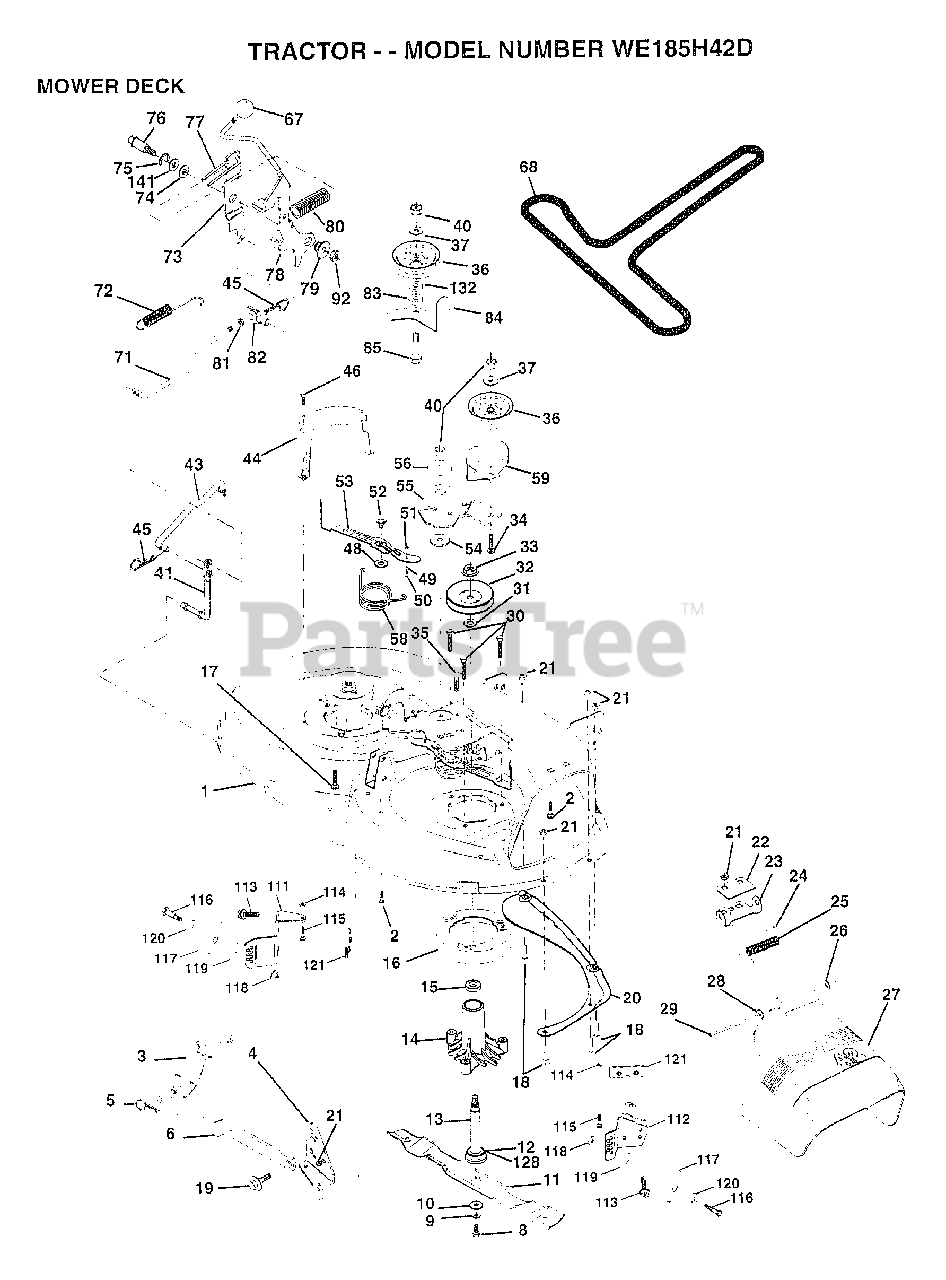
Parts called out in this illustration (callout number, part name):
1	DECK.WELD.42.
2	BOLT
3	BRKT ASM SWAY BAR
4	BRKT DECK SW BAR
8	BLADE BOLT
10	WASHER.HARD.BLADE
11	"BLADE.42"" HIPERF"
12	BEARING.BALL
14	HSG ASM MANDREL
15	BEARING
16	STRIPPER RND MWR
17	BOLT RDHD 3/8-16
18	BOLT
19	BOLT SHD 5/16-18
20	BAFFLE VORTEX 42
22	STIFFENER BRKT
23	DEFLECTOR BRKT
24	CAP-SLEEVE LT
25	SPRING TORSION
26	NUT PUSH M
27	DEFLECTOR.SHIELD
28	WASHER
29	HINGE ROD
30	"SCREW-THD ROLL,WA"
31	WASHER
32	PULLEY.MANDREL.42
34	BOLT
35	XMAS TREE FASTNER
36	FLAT IDLER PULLEY
37	WASHER
41	PIVOT ROD
43	ROD CLUTCH W/NIBS
44	GUARD MAND LH BLK
46	SCREW.1/4-20X5/8
48	HARD SMALL WASHER
49	ROLLER ASM-CAM
50	SHOULDER BOLT
51	LOCKNUT
52	BOLT.SHLD.5/16-18
54	HARDENED WASHER
55	ARM-IDLER
56	SPACER RETAINER
58	SPRING TORSN BRAK
59	GUARD IDLER TUV
67	KNOB.RD.7/16-14
68	BELT.V.T-PATH
71	ROD CLUTCH 38/42
72	RETURN SPRING
73	CLUTCH ARM SECOND
74	WASHER
75	RING
76	SHOULDER BOLT
77	SPRING KEEPER
78	LEVER.ASM.CLUTCH
79	BUSHING
80	SPRING.CLUTCH.MWR
81	NUT
82	TRUNION ADJ
83	WASHER
84	"KEEPER-BELT,FIXED"
85	BOLT RDHD 3/8-16
92	NUT
111	BRACKET.GWHL.LH.
112	BRACKET.GWHL.RH.
113	SCREW
116	BOLT M
117	WHEEL.GAGE.BLK.PL
118	LOCKNUT
119	WASHER
120	WASHER
121	BRACKET.EXTRD.GWL
128	WASHER.FELT.
132	WASHER GT
141	WASHER .T
